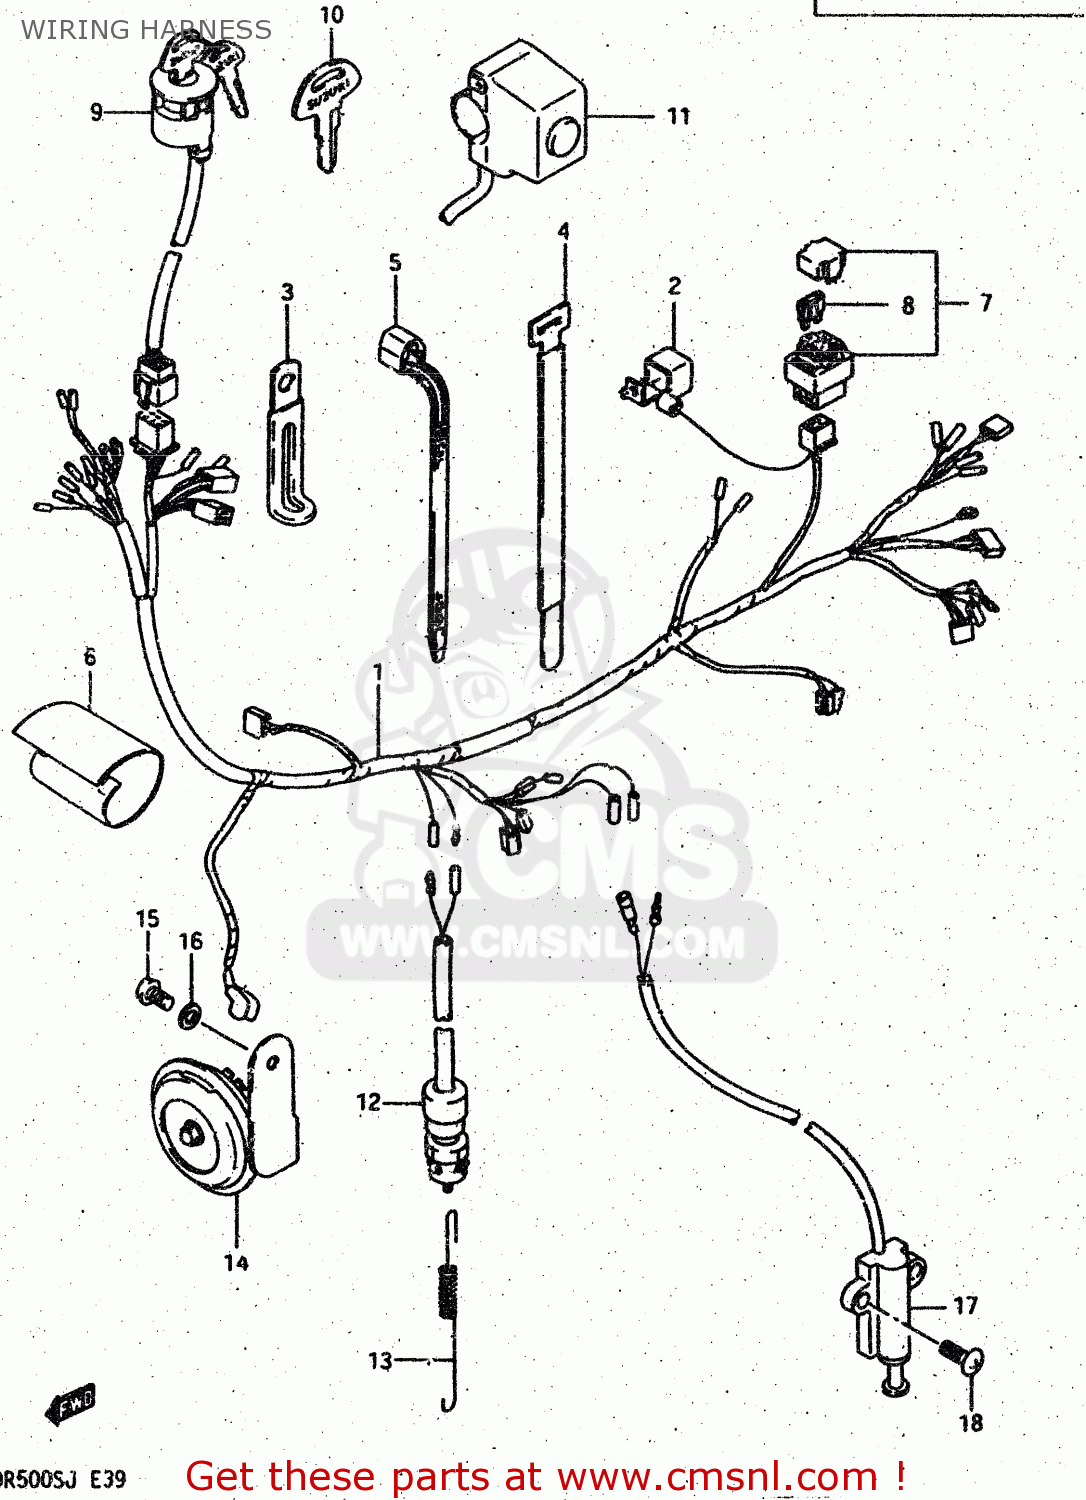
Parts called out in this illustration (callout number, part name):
1	HARNESS, WIRING
2	CAP,BATTERY PLUS TERMINAL
3	CLAMP
4	CLAMP
5	CLAMP(L:125)
6	COVER,WIRING HARNESS
7	BOX ASSY,FUSE
8	FUSE(15A)
9	SWITCH ASSEMBLY,IGNITION
10	KEY,BLANK
11	SWITCH ASSY,ENGINE STOP
12	SWITCH ASSEMBLY,STOP LAMP
13	SPRING
14	HORN ASSEMBLY
15	SCREW
16	WASHER,LOCK
17	SWITCH ASSY, SIDE STAND
18	SCREW
